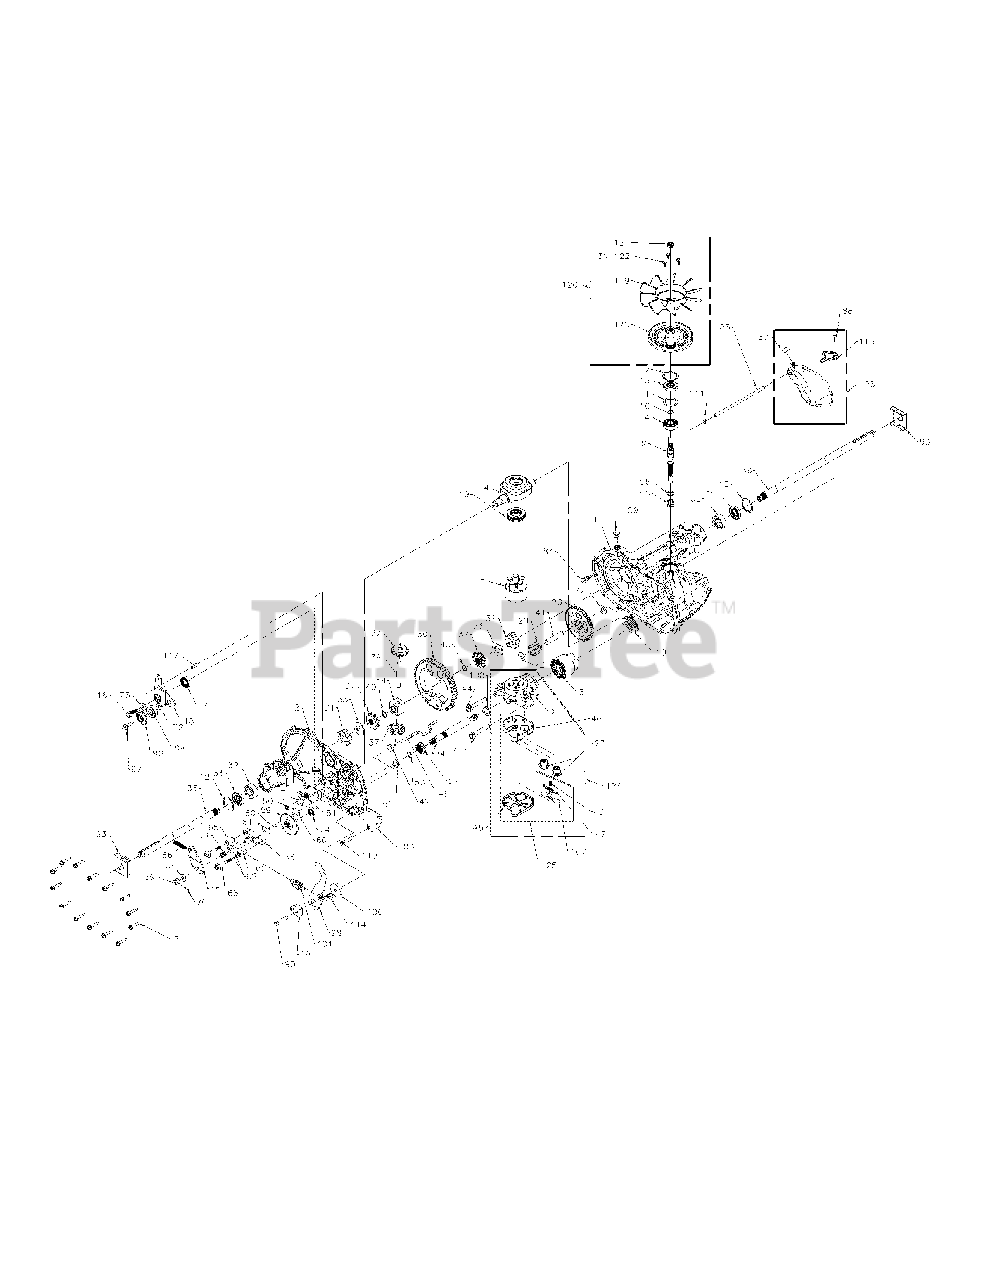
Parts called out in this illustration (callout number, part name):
1	Main Housing, Assembly
1	Main Housing
1	Bushing .865 X .985 X .790
1	Pin, Standard Headless
2	Side Housing, Assembly
2	Side Housing
2	Bushing .865 X .985 X .790
2	Bushing .624 X .719 X .562
3	Center Section, Assembly
3	Center Section
3	Bushing .707 X .788 X .591
4	Trunnion, Swashplate
5	Block, Assembly
5	Block, Cylinder
5	Piston
5	Spring, Compression
5	Washer, Thrust
7	Screw, Hex Flange 1/4-20 X 1.25
9	Shaft, Input
10	Ring, Retaining
12	Ring, Retaining
13	Seal, Lip 17 X 40 X 7
14	Bearing Ball 17mm ID X 40mm OD X 12mm
16	Bolt, Hex Flange Head 5/16-24 X .94 (Patch)
17	Seal, Lip 18 X 32 X 7
18	Arm, Control
19	Bearing, Thrust 30 X 52 X 13
23	Check Plug Assembly, .027 Washer
24	Shaft, Motor
27	Gear, 13T Pinnion
28	Gear, 10T/48T
29	Gear 10T Jackshaft
30	Gear, 60T Bull
31	Bushing, Sleeve (Inboard)
32	Bushing, Sleeve .75 X 1.575 X .625
33	Washer, 3/4 ID X 1-1/2 OD X .13 THK
34	Seal, Lip .75 X 1.577 X .250
35	Shaft, Axel .75 X 12.14 (Keyed, R.H.)
36	Shaft, Axel .75 X 17.74 (Keyed, L.H.)
37	Kit, Miter Gear
37	Gear, Miter 12T (Splined)
37	Gear, Miter 12T (.50 ID)
37	Bulletin, Miter Gear
39	Shaft, Diff
40	Ring, Spiral Retaining
41	Pin, Jackshaft
42	Magnet, Ring
43	Spring, Bypass
44	Bolt, Hex Flange 3/8-24 X 2.5
45	Bottom, Filter
46	Base, Filter with Poppet
47	Actuator, Bypass
48	Rod, Actuator Bypass
49	Arm, Bypass
50	Ring, Retaining .250 External
51	Seal, Lip .250 X .750 X .250 TC
52	Washer, Flat 5/8 ID X 1.0 OD X .05
53	Ring, Retaining
54	Bushing, Center Block
55	Spring, Block
56	Washer, Thrust
58	Kit, Brake Yoke
58	Yoke, Brake
58	Bolt, SQ.HD. 5/16-24- Ribbed
59	Rotor, Brake
60	Puck, Brake
61	Plate, Puck
62	Pin, Brake Actuating
63	Screw, Special Flange 1/4-20 X 2 W/ Patch
66	Spring, Brake Arm Bias
68	Arm, Brake
69	Nut, Castle 5/16-24
70	Pin, Cotter 3/32 X 3/4
71	Spring, Compression Brake Anti-Drag
72	Washer, HT .5 ID X 1 OD X .032
73	Washer, Flat 11/32 ID X 7/8 OD
74	Seal, Lip .625 X 1.0 X .25
84	Fitting, 5/16 SAE 5/32 Tube
85	Hose, Expansion Tank
87	Cap, Expansion
88	Bolt, Self Tapping 10-32 X1/2
93	Spring Clip, Housing Thrust
94	Bearing, Ball .62 ID X 1.38 X .44
95	Screw, Socket Head Cap 5/16-24 X 1-1/2
96	Spacer, Locating
97	Screw, Countersunk 5/16-18 X 1
98	Arm, Return
99	Puck, Adjusting
100	Washer, .32 OD X 1.60 ID X .24
101	Spring, Extension Double Loop
102	Spacer, .260 ID X .560 OD X .870
103	Bracket, Torque
107	Deflector
108	Washer, Motor Shaft .71 ID X 1.15 OD X .030 THK
109	Plug, 9/16-18 (Metal)
110	Screw, Torx Head 5/16-18 T.F.
111	O-Ring .103 ID X .299 OD
113	Bracket, Support Expansion Tank
114	Spring Guide
117	Pin, Spring
119	Fan, 7 IN 10 Blade
120	Pulley, 4.79 Inch
121	Nut, Hex Lock 1/2-20 (Nylon Insert)
122	Screw, Tapping, Hex Washer Head, 12-24 X .50
124	Center Section, Filter, Bypass Assembly
124	Center Section
124	Base, Filter with Poppet
124	Check Plug Assembly, .027 Washer
124	Spring, Bypass
124	Actuator, Bypass
124	Deflector
124	Bottom, Filter
124	Bushing, .707 X .788 X .591
125	Filter Assembly
125	Bottom, Filter
125	Base, Filter with Poppet
125	Spring, Bypass
125	Actuator, Bypass
125	Deflector
126	Kit, Fan/Pulley
126	Fan, 7 IN 10 Blade
126	Pulley, 4.79 Inch
126	Nut, Hex Lock 1/2-20 (Nylon Insert)
126	Screw, Tapping, Hex Washer Head, 12-24 X .50
128	Kit, Expansion Tank
128	Tank, Expansion
128	Cap, Expansion
128	Bolt, Self Tapping 10-32 X1/2
128	Bracket, Support Expansion Tank
128	Seal, O-Ring Kit
128	Seal, Lip 17 X 40 X 7
128	Seal, Lip 18 X 32 X 7
128	Seal, Lip .75 X 1.577 X .250
128	Seal, Lip .250 X .750 X .250 TC
128	Seal, Lip .625 X 1.0 X .25
128	O-Ring .103 ID X .299 OD
